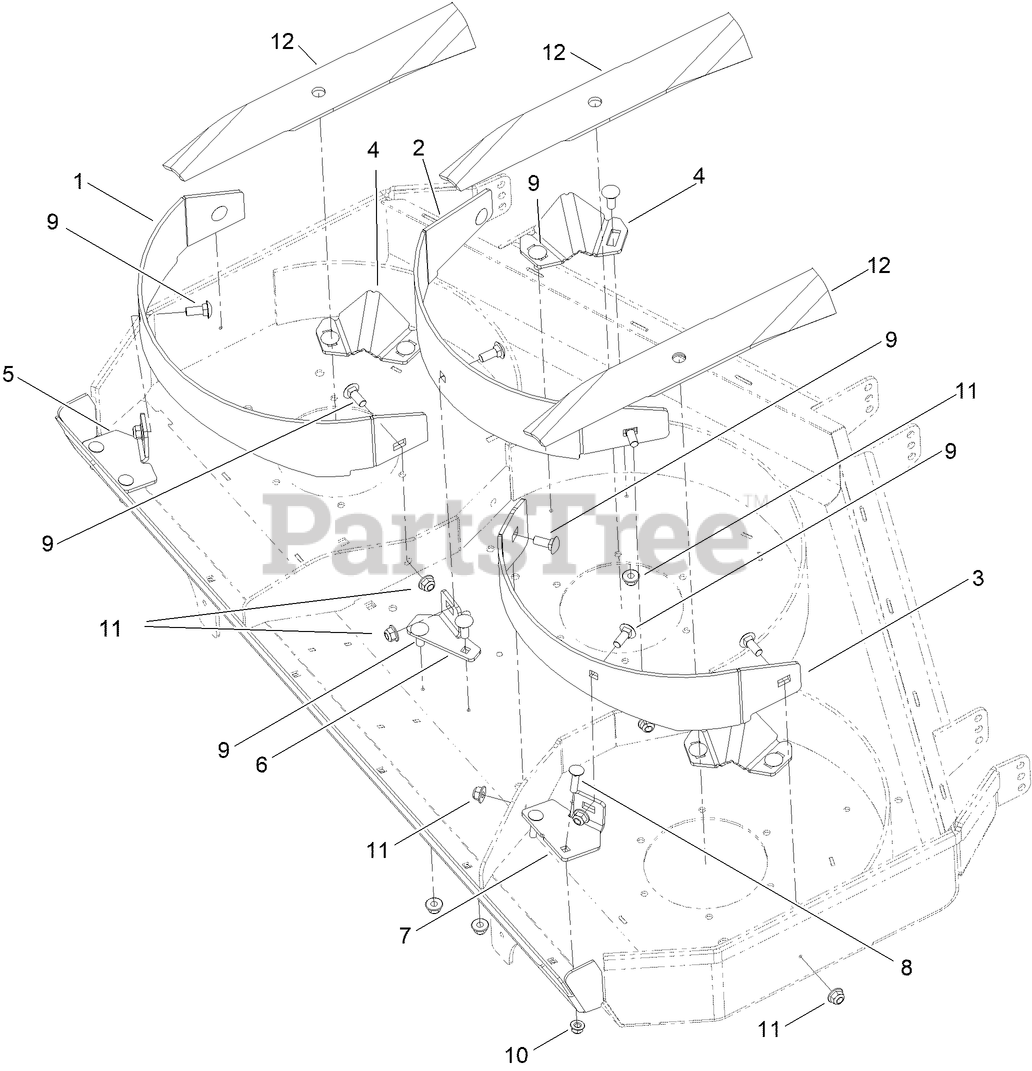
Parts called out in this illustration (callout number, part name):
1	BAFFLE- MULCHING RH, 48 (RD)
2	BAFFLE- MULCHING CTR, 48 (RD)
3	BAFFLE- MULCHING LH, 48 (RD)
5	SUPPORT, RH BAFFLE (RD)
6	SUPPORT, CTR BAFFLE (RD)
7	SUPPORT, LH BAFFLE (RD)
8	SCREW-CARR
9	BOLT-CARR
10	NUT-HF, NI
11	NUT-HF, NI
12	BLADE-ROTARY, RECYCLING 16.5IN
99	NUT-HF, NI
99	SCREW-HHF
